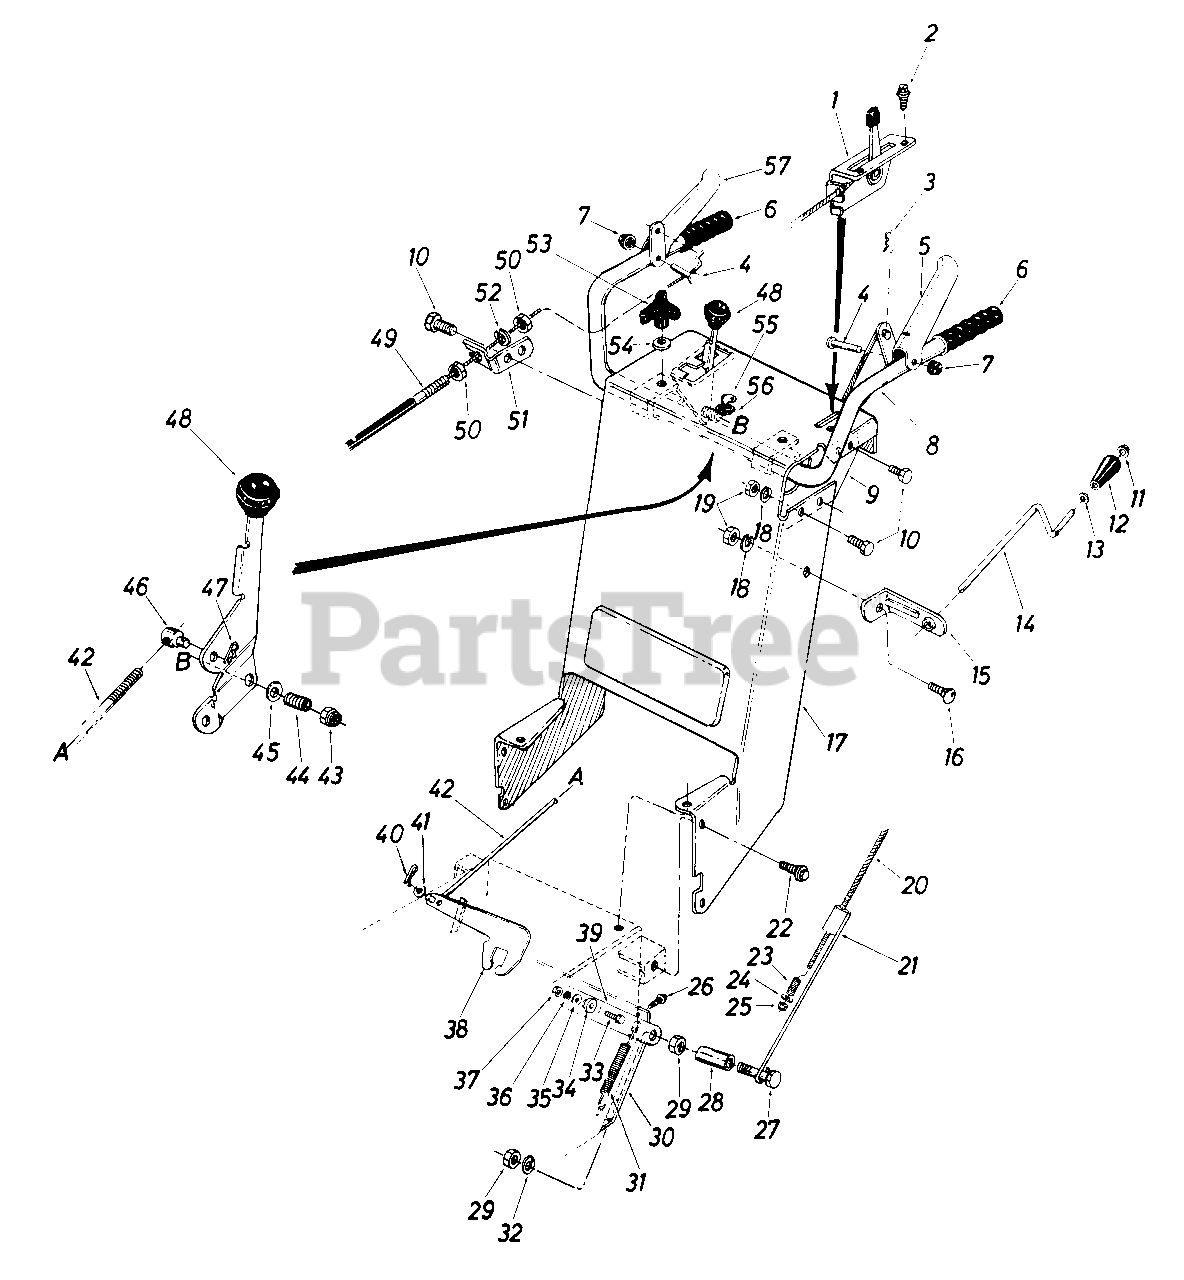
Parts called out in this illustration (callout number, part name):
1	Throttle Control Ass'y. Comp.
2	Hex Wash. Self-Tap Scr. #8 x .50" Lg.
3	Cotterpin 3/32" Dia. x 1.00" Lg.
4	Clevis Pin .375" Dia. x 1.88" Lg.
5	Auger Clutch Grip Ass'y. - L.H.
6	Grip Handle
7	Push Cap .375" Rod - Black
8	Handle Ass'y.
9	Handle Support Brkt.
10	Hex Bolt 5/16-24 x .62" Lg.
11	Push Nut 3/8" Rod
12	Black Knob - 3/8" Dia. Hole
13	Fl-Wash. .385" I.D. x .62" O.D. x .063"
14	Chute Crank .38" Dia. x 35" Lg.
15	Chute Control Brkt.
16	Carriage Bolt 5/16-18 x .62" Lg.
17	Handle Panel Ass'y.
18	L-Wash. 5/16" I.D.
19	Hex Nut 5/16-24 Thread
20	Lockout Cable - 30.5" Lg.
21	Auger Clutch Rod Ass'y.
22	Hex Wash. Self-Tap Scr. 5/16-24 x .50" Lg.
23	Compression Spring
24	Fl-Wash. .28" I.D. x .74" O.D. x .063"
25	Hex Ins. L-Nut 3/18-16 Thread
26	Hex Wash. Self-Tap Scr. 5/16-24 x .50" Lg.
27	Hex Bolt 1/4-28 x 2.5" Lg.
28	Spacer .38" I.D. x .50" O.D. x 1.44" Lg.
29	Hex Nut 1/4-28 Thd.
30	Frame Cover
31	Ext. Spring .38" O.D. x 3.25" Lg.
32	L-Wash. 1/4" I.D.
33	Hex Sems Scr. 5/16-18 x .75" Lg.
34	Shoulder Spacer
35	Fl-Wash. .344" I.D. x 1.125" O.D. x .125"
36	L-Wash. 5/16" I.D.
37	Hex Cent. L-Nut 5/16-18 Thd.
38	Shifting Brkt.
39	Thrower Clutch Brkt.
40	Cotterpin 3/32" Dia. x 1.0" Lg.
41	Fl-Wash. .344" I.D. x .62" O.D. x .063"
42	Shifting Rod
43	Hex Ins. L-Nut 3/8-24 Thd.
44	Compression Spring .39" 1.0. x .88" Lg.
45	Bell-Wash. .40" I.D. x .88" O.D. x .06"
46	Ferrule - Engagement
47	Cotterpin 3/32" Dia. x 1.0" Lg.
48	Shift Handle Ass'y.
49	Drive Clutch Control Cable
50	Hex Jam Nut 5/16-24 Thd.
51	Cable Support Brkt.
52	L-Wash. 5/16" I.D.
53	Three Arm Knob 5/16-18 Thd.
54	Bell-Wash. .345" I.D. x .62" O.D. x .063"
55	Ignition Key
56	Ignition Switch
57	Drive Clutch Grip - R.H.
